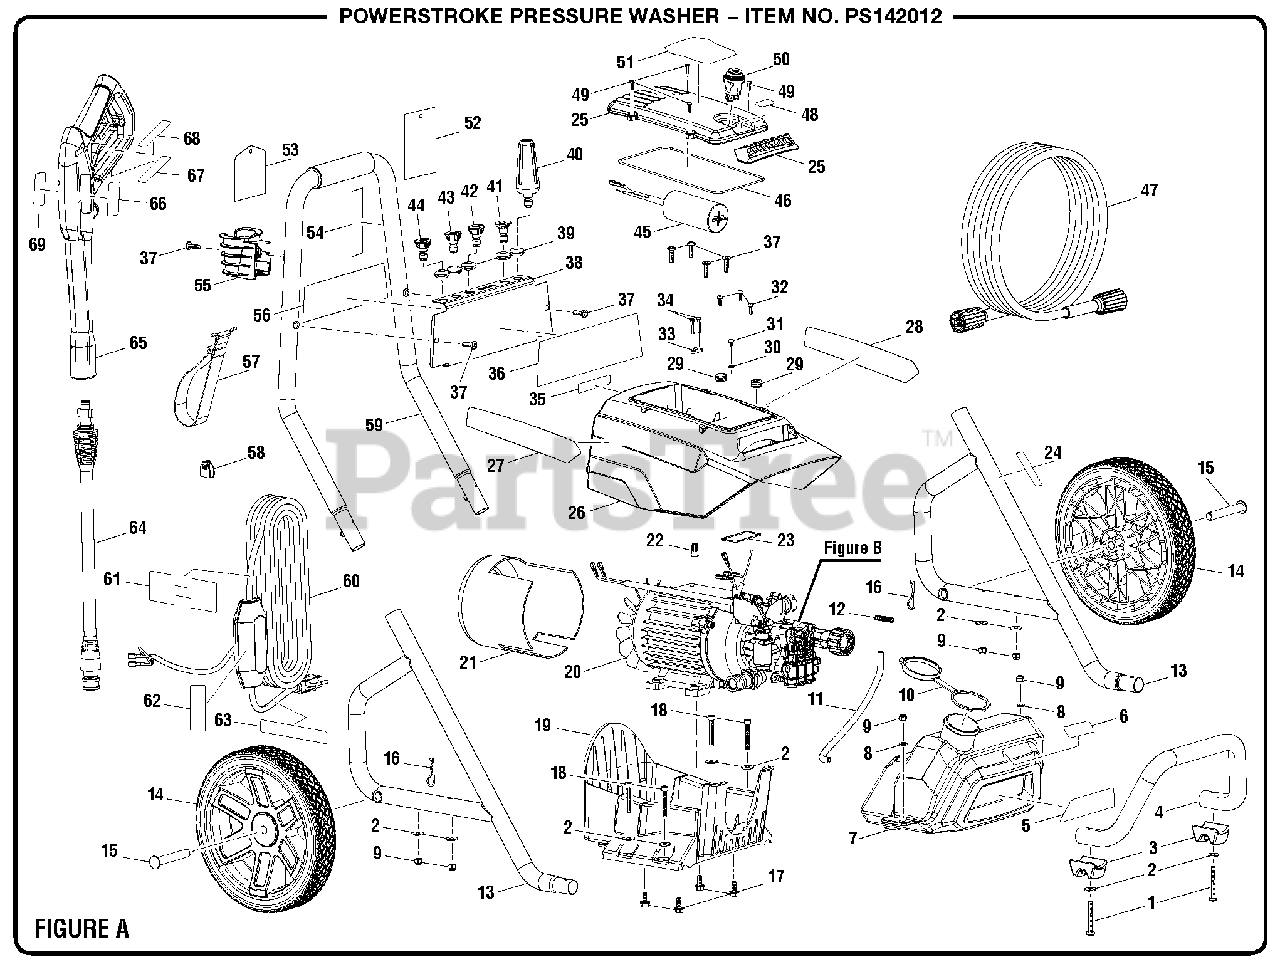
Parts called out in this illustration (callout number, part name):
1	Screw (M6 x 48 mm, T30 Torx Pan Hd.)
2	Washer (M6)
3	Rubber Foot
4	Front Frame
5	Logo Label
6	Soap Tank Label
7	Soap Tank
8	Washer (M6)
9	Lock Nut (M6)
10	Soap Tank Cap
11	Chemical Siphon Tube
12	Compression Spring
13	Frame Assembly
14	Wheel (10 in.)
15	Wheel Axle
16	Cotter Pin
17	Bolt (M6 x 16 mm, Flange Hex Hd.)
18	Bolt (M6 x 40 mm, Socket Hex Hd.)
19	Lower Housing
20	Induction Motor/Pump Assembly
21	Motor Housing
22	Wire Connector
23	Rubber Gasket
24	Inquires Label
25	Upper Housing Assembly
26	Motor Shroud
27	Side Label (Right)
28	Side Label (Left)
29	Rubber Grommet
30	Washer (M4)
31	Screw (M4 x 16 mm, Pan Hd.)
32	Bolt (M4 x 12 mm, Pan Hd.)
33	Cord Clamp
34	Screw (M3.5 x 20 mm, Pan Hd.)
35	Try Another Outlet Label
36	Performance Label
37	Bolt (M6 x 20 mm, Pan Hd.)
39	Rubber Nozzle Grommet
40	Turbo Nozzle
41	Soap Nozzle
42	40deg Nozzle
43	25deg Nozzle
44	15deg Nozzle
45	Capacitor
46	Rubber Gasket
47	Hose (25 ft.)
48	On/Off Label
49	Screw (M4.2 x 15 mm, Pan Hd.)
51	Motor Cover Label
52	Nozzle Hangtag
53	Danger Hangtag (Spanish)
54	Quick Start Label
55	Handle Holder
56	Danger Label
57	Hose Holder Strap
58	Cord Clip
59	Handle Assembly
60	Power Cord Assembly
61	Cordwrap Warning Label
62	Plug Label
63	Outlet Cord Wrap Label
64	Spray Wand
65	Trigger Handle Assembly
66	Trigger Handle Warning Label
67	Trigger Handle Rating Label
68	Trigger Handle Warning Label (French/Spanish)
69	Trigger Handle Warning Logo Label
